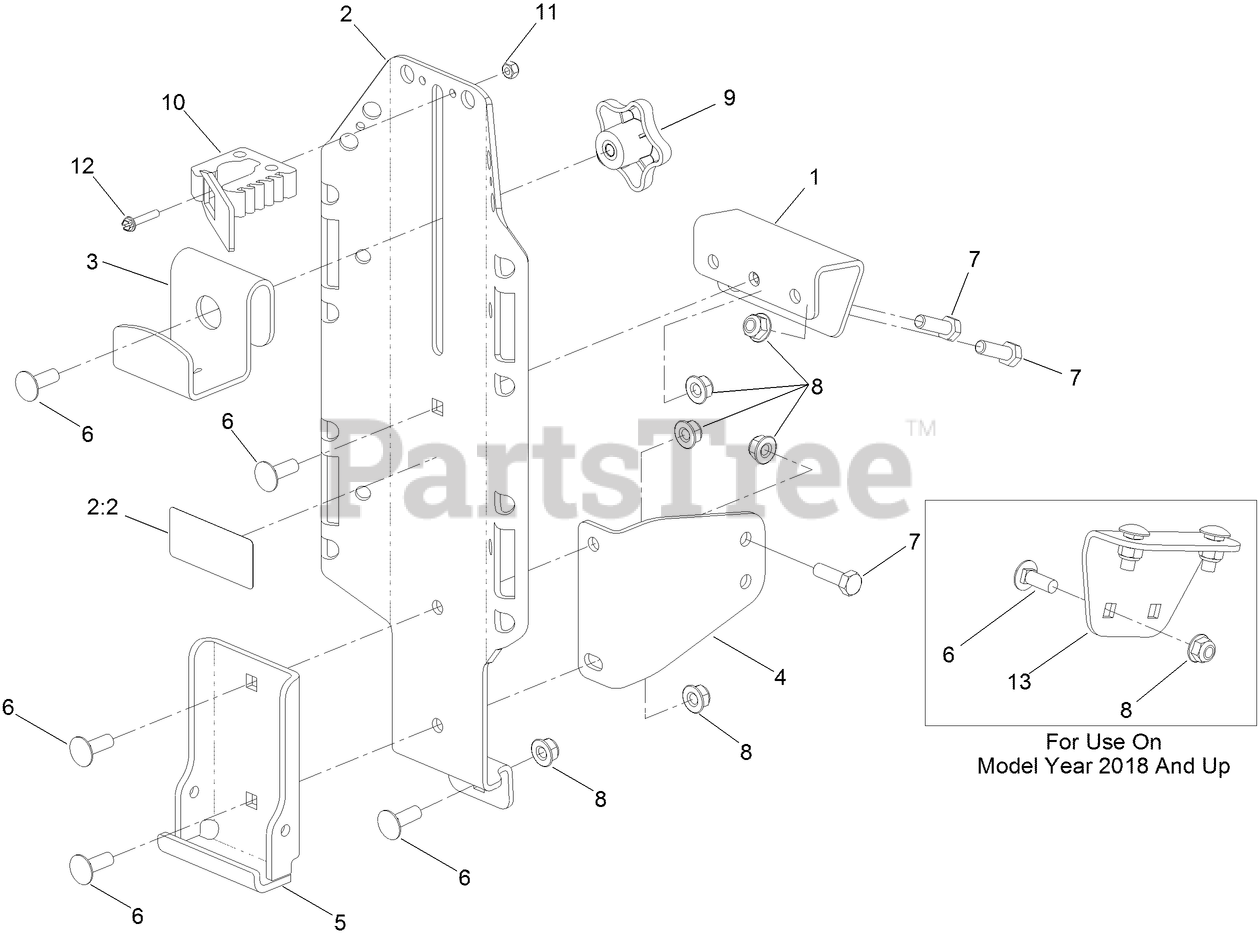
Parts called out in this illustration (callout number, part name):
1	MOUNT-BUCKET, UPPER
2	MOUNT BRACKET ASM
2:2	DECAL-WEIGHT, MAXIMUM
3	BRACKET-TOP
4	BRACKET-SUPPORT, LOWER
5	BRACKET-SUPPORT, HINGE
6	BOLT-CARR
7	SCREW-HH
8	NUT-HF, NI
9	KNOB-HANDLE
10	CLAMP-QUICK FIST, MINI
11	NUT-LOCK
12	SCREW-SHWH
13	BRACKET-SUPPORT, INNER
